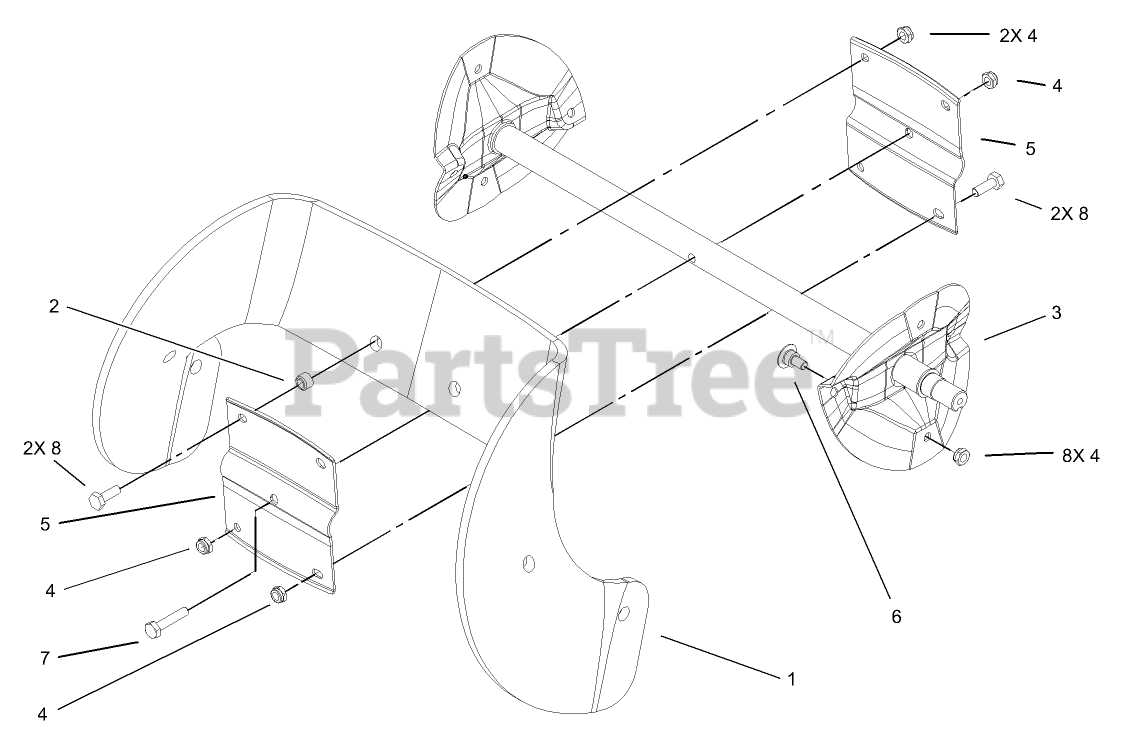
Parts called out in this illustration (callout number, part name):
1	BLADE-ROTOR
2	SPACER-BLADE, ROTOR
4	NUT-LOCK, NI
5	HALF-ROTOR
6	SCREW
7	SCREW-HH
8	SCREW-HH
